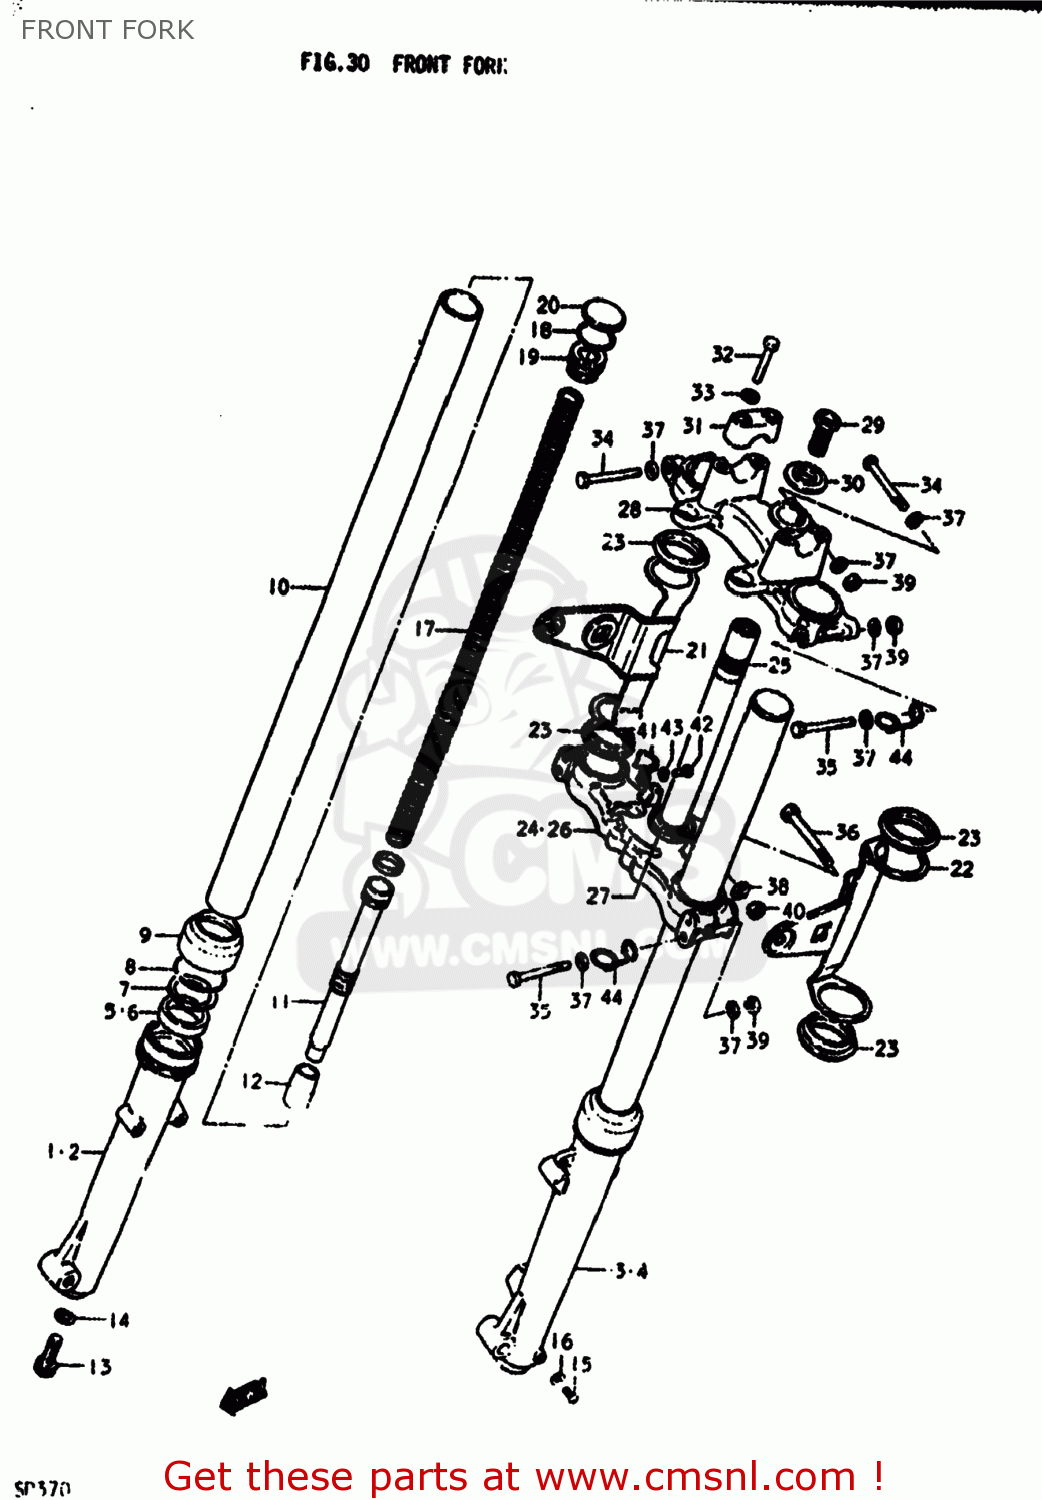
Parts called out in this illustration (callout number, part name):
0	DAMPER ASSEMBLY,LEFT
1	TUBE,OUTER,RIGHT
2	TUBE,OUTER,RIGHT
3	TUBE,OUTER,LEFT
4	TUBE,FORK,LEFT,OUTER
5	OIL SEAL,FRONT FORK
6	OIL SEAL,FRONT FORK
7	RING,FORK BACK UP
8	CIRCLIP,FORK OIL SEAL
9	SEAL,DUST
10	TUBE,FORK,INNER
11	TUBE,OUTER,LEFT
12	PIECE,OIL LOCK
13	BOLT,FORK CYLINDER(10X25)
14	GASKET (NAS)
15	SCREW
16	GASKET,DRAIN,PLUG (NAS)
17	SPRING
18	O RING
19	CAP,FORK INNER TUBE
20	CAP,FRONT FORK
21	BRACKET,HEADLAMP,RIGHT
22	BRACKET,HEADLAMP,LEFT
23	CUSHION,HEADLAMP BRACKET
24	STEM,STEERING
25	STEM,STEERING
26	STEM,STEERING
27	RACE,STEERING OUTER LWR
28	HEAD,STEERING STEM
29	BOLT,STEERING STEM HEAD
30	WASHER
31	HOLDER,HANDLEBAR
32	BOLT
33	LOCK WASHER
34	BOLT 8X55
35	BOLT
36	BOLT 10X60
37	WASHER
38	LOCK WASHER
39	NUT
40	NUT
41	CLIP,BRAKE CABLE
42	SCREW
43	LOCK WASHER
44	GUIDE,CABLE
